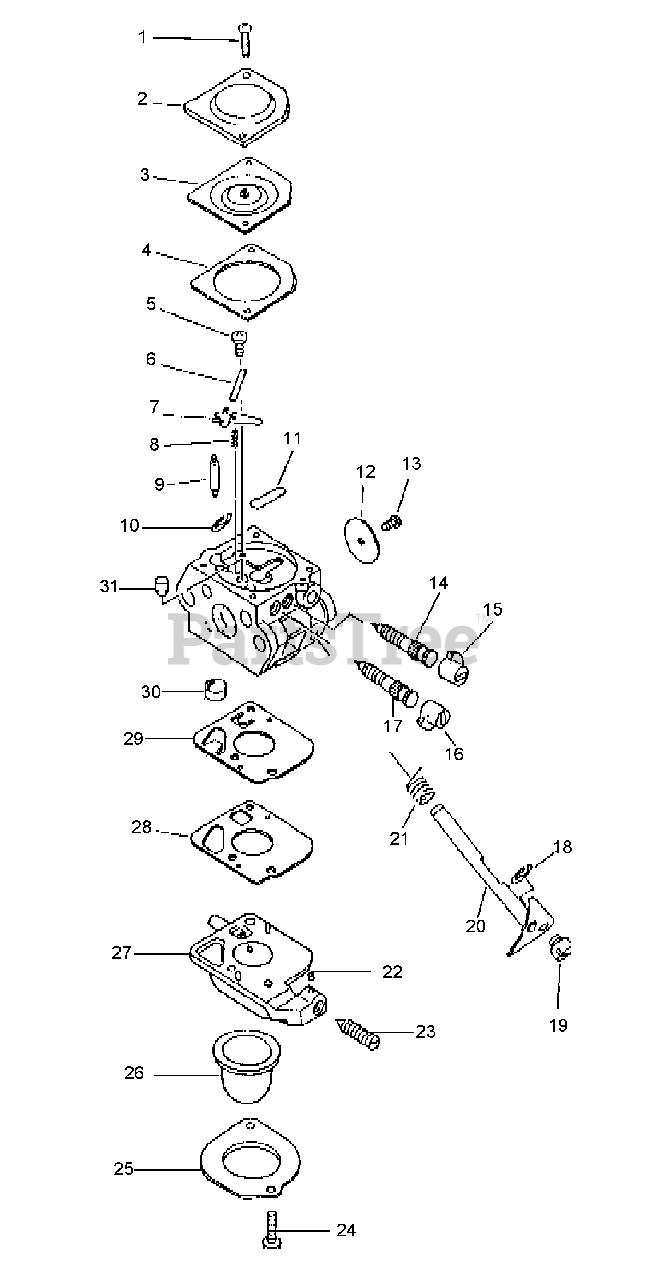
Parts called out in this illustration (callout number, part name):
2	COVER, METERING DIAPHRAGM
3	DIAPHRAGM, METERING
4	GASKET, METERING
6	PIN, METERING LEVER
7	LEVER, METERING
8	SPRING, METERING LEVER
9	VALVE, NEEDLE
11	PLUG, WELCH
12	VALVE, THROTTLE
14	NEEDLE, LOW SPEED
15	CAP, LIMITER - WHITE
16	CAP, LIMITER - RED
17	NEEDLE, HIGH SPEED
20	SHAFT, THROTTLE
21	SPRING, THROTTLE RETURN
22	PIECE, FRICTION
23	SCREW, IDLE ADJUST
25	RETAINER
26	BULB, PURGE
27	BODY ASSY, PURGE
28	GASKET, PUMP
29	DIAPHRAGM, PUMP
30	STRAINER
31	NOZZLE, CHECK VALVE
